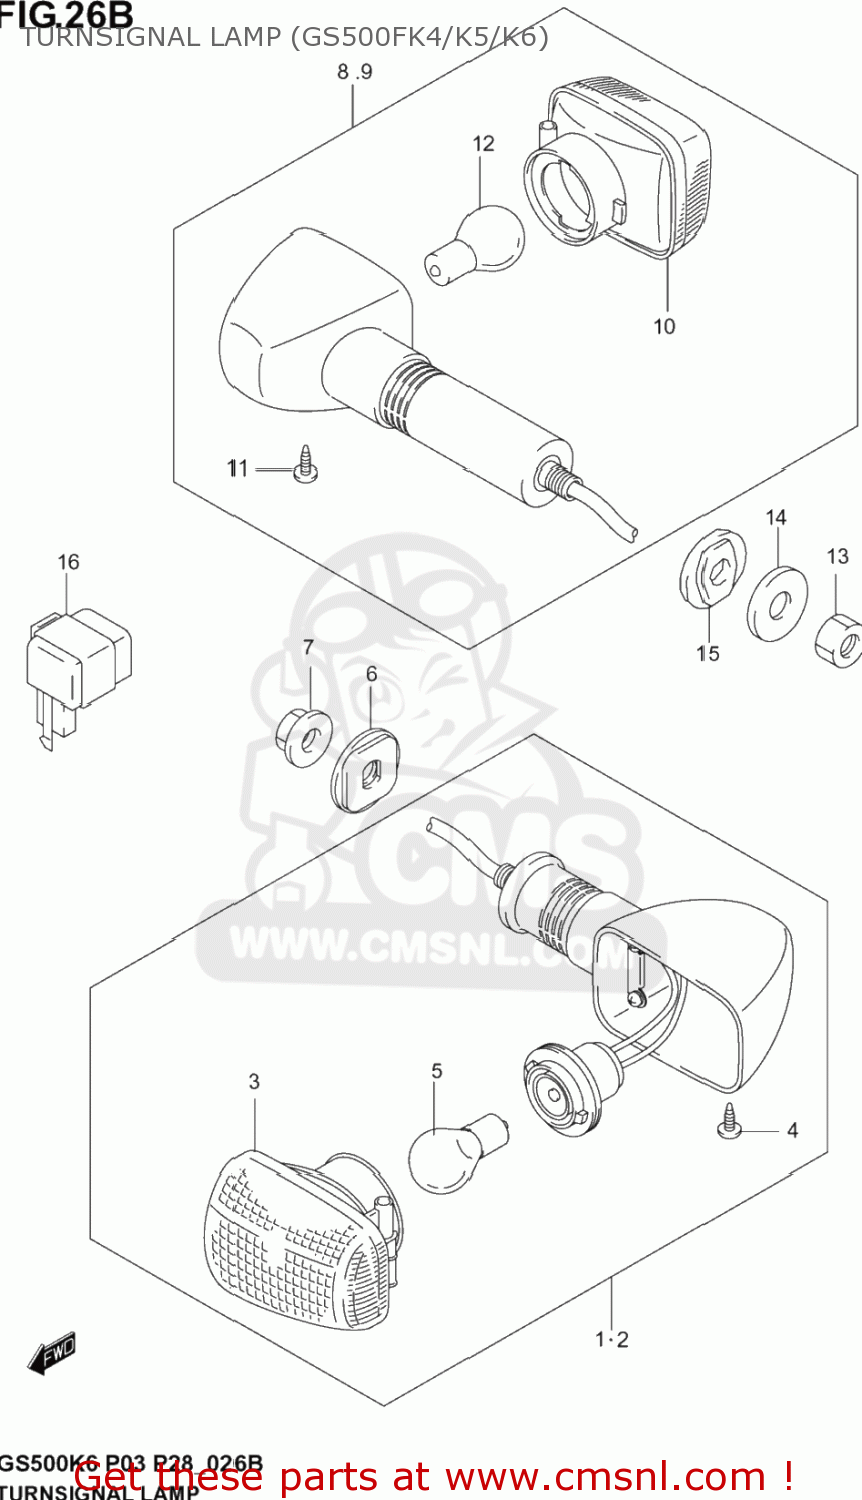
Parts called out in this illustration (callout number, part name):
1	LAMP ASSY FRON
2	LAMP ASSY FR
3	LAMP UNIT
4	SCREW
5	BULB(12V21W)
6	PLATE,FR TURN
7	NUT
8	LAMP ASSY REAR
9	LAMP ASSY REAR
10	LAMP UNIT
11	SCREW
12	BULB(12V21W)
13	NUT
14	WASHER(10.5X30X2.3)
15	SPACER,RR TURNSIGNAL
16	RELAY ASSY, TURNSIGNAL
